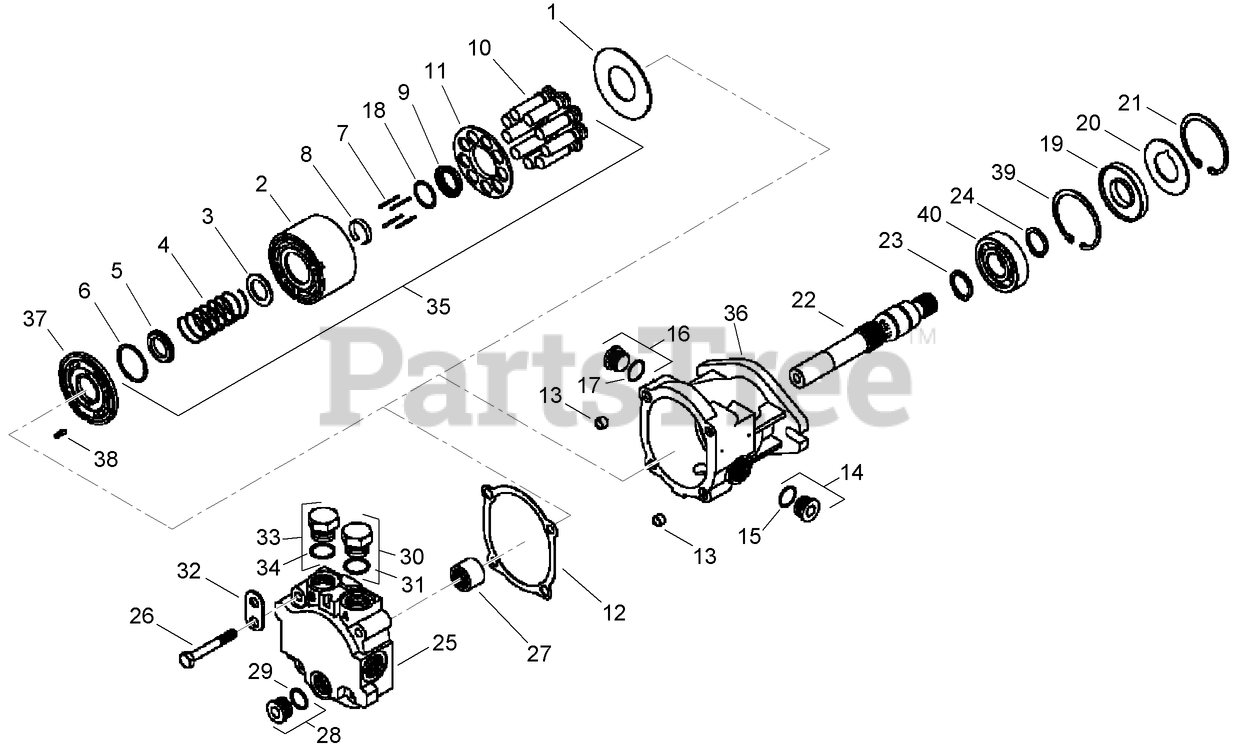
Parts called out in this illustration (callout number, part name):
1	PLATE-Thrust
2	CYLINDER BLOCK KIT
4	SPRING-Cylinder Block
5	RETAINER-Cylinder Block Spring
6	RING-RETAINING
7	PIN-Slipper Hold Down
8	RETAINER-Hold Down Pin
9	GUIDE-Slipper Retainer
10	Asm-Piston
11	RETAINER-Slipper
12	WASHER-Thrust
13	Block-Cylinder
14	PLUG-Socket Head
15	O-RING
16	PLUG-Socket Head
17	O-RING
18	PIN-Spring
19	SEAL-BEARING, CARRIER
20	WASHER-SUPPORT, SEAL
21	RING-RETAINING
23	RING-RETAINING
24	RING-RETAINING
25	CAP-End
26	Screw
27	BEARING-Needle
28	Plug
29	O-RING
30	Plug
31	O-RING
32	BRACKET-Lifting
33	Plug
34	O-RING
35	GASKET-End Cap
36	HOUSING-Fixed
37	PLATE-Valve
38	PIN-Slotted
39	RING-RETAINING
40	Bearing-Ball
